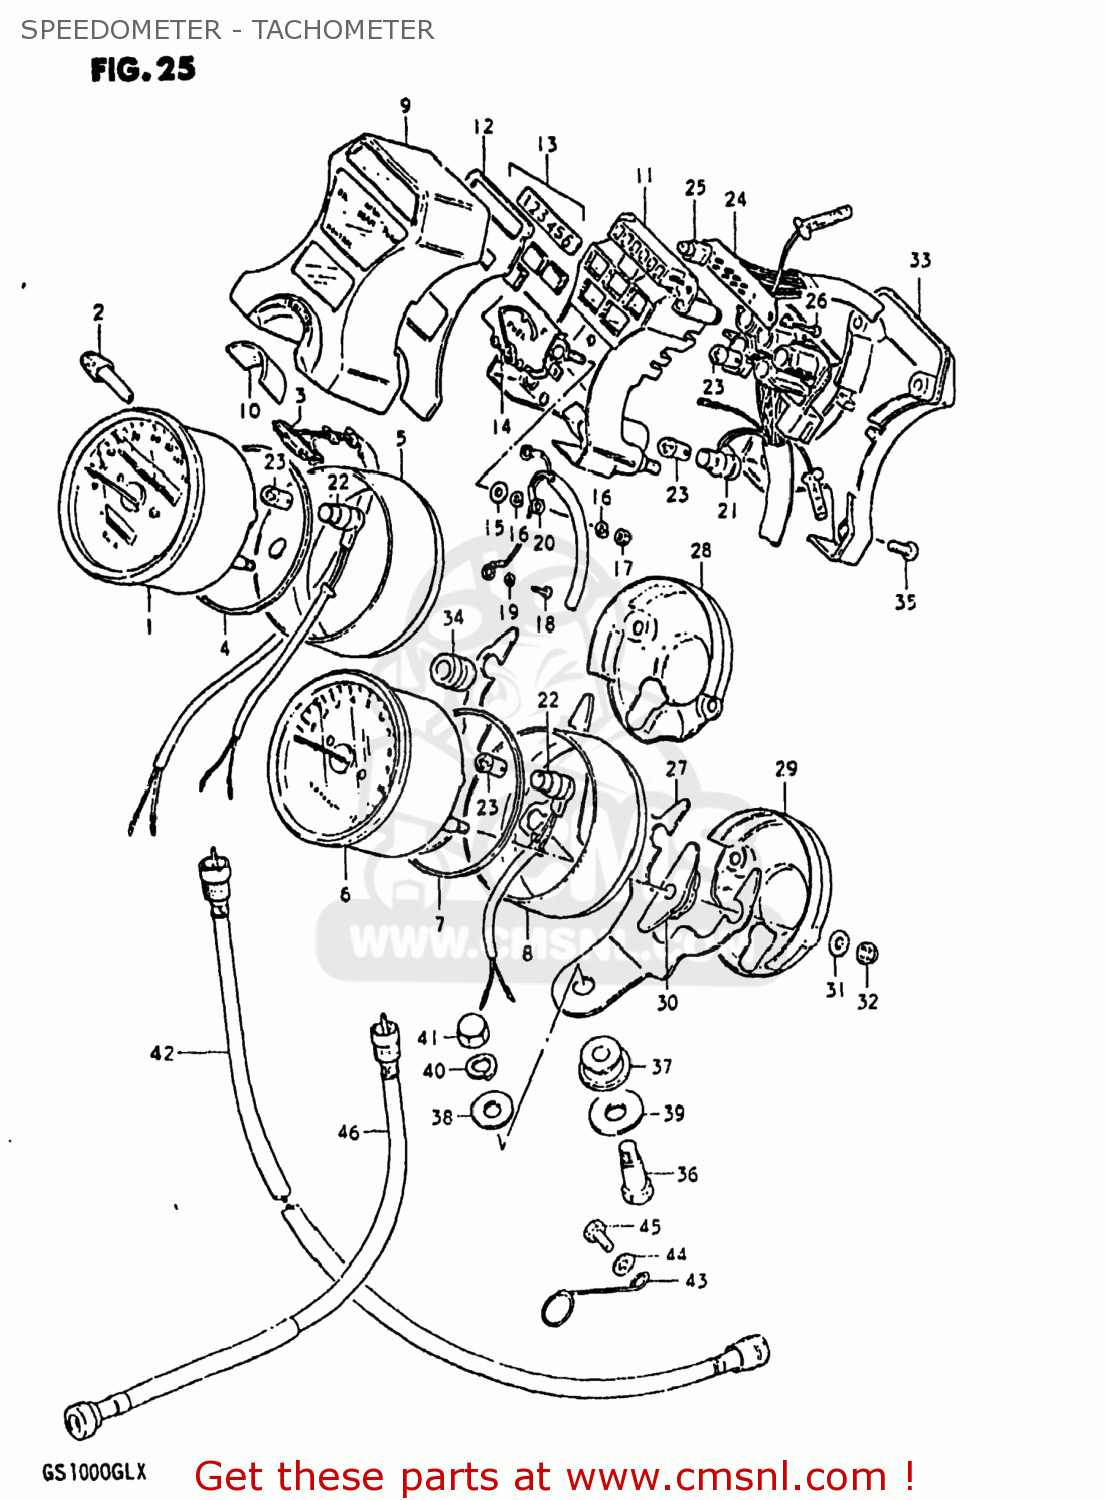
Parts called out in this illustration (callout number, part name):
1	METER,SPEEDOMETER
2	KNOB
3	WIRE,LEAD SWITCH
4	CUSHION
5	COVER,SPEEDOMETER
6	TACHOMETER
7	CUSHION
8	COVER,TACHOMETER
9	CASE,PILOT BOX,OUTER
10	SEAL,IGNITION SWITCH
11	CASE, PILOT BOX INNER
12	PLATE,PILOT BOX
13	LENS SET,PILOT
14	METER,FUEL
15	WASHER
16	LOCK WASHER
17	NUT
18	SCREW
19	LOCK WASHER
20	LEAD WIRE, FUELMETER
21	SOCKET
22	SOCKET,METER
23	BULB(12V3.4W,T10)
24	INDICATOR ASSEMBLY,GEAR POSITION
25	BULB(14V1.12W)
26	SCREW
27	BRACKET,COMBINATION METER
28	ORNAMENT,SPEEDOMETER
29	COVER,TACHOMETER
30	CUSHION,METER
31	WASHER
32	NUT
33	COVER,PILOT BOX,UNDER
34	CUSHION,PILOT BOX
35	SCREW,PILOT BOX
36	BOLT
37	CUSHION,METER
38	WASHER(8.5X23X1.2)
39	WASHER
40	LOCK WASHER
41	NUT
42	CABLE ASSEMBLY,SPEEDOMETER
43	GUIDE,SPEEDOMETER CABLE
44	WASHER
45	BOLT, UPPER
46	CABLE ASSEMBLY,TACHOMETER
